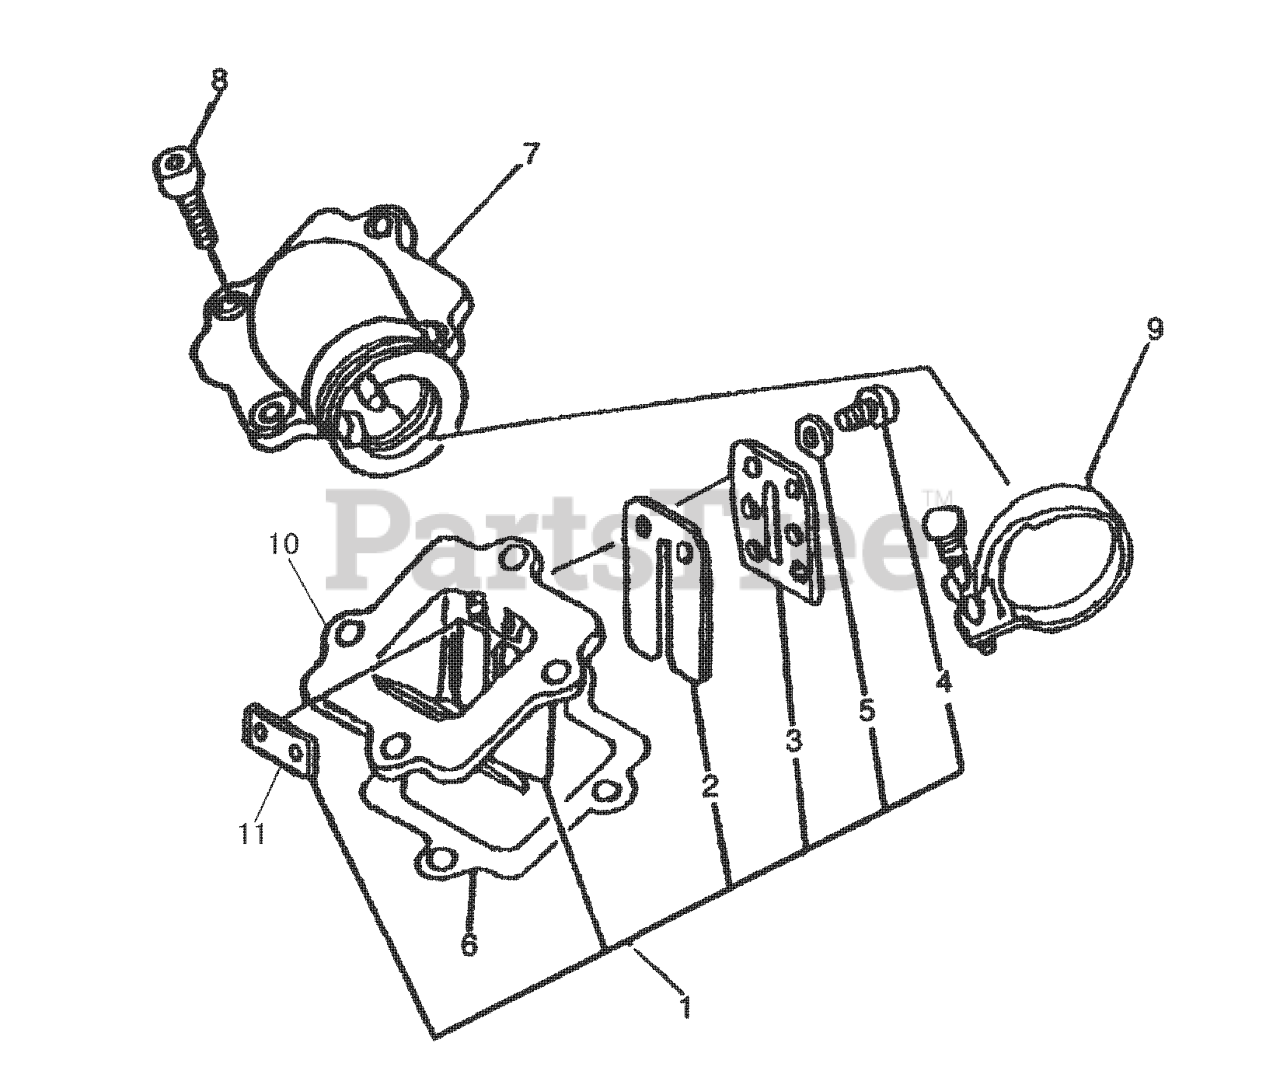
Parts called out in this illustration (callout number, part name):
1	REED VALVE ASSY
2	REED VALVE
3	REED VALVE STOPPER
6	VALVE SEAT GASKET
7	PIPE, INTAKE
9	CLAMP, HOSE
10	VALVE SEAT
11	REED VALVE GASKET
